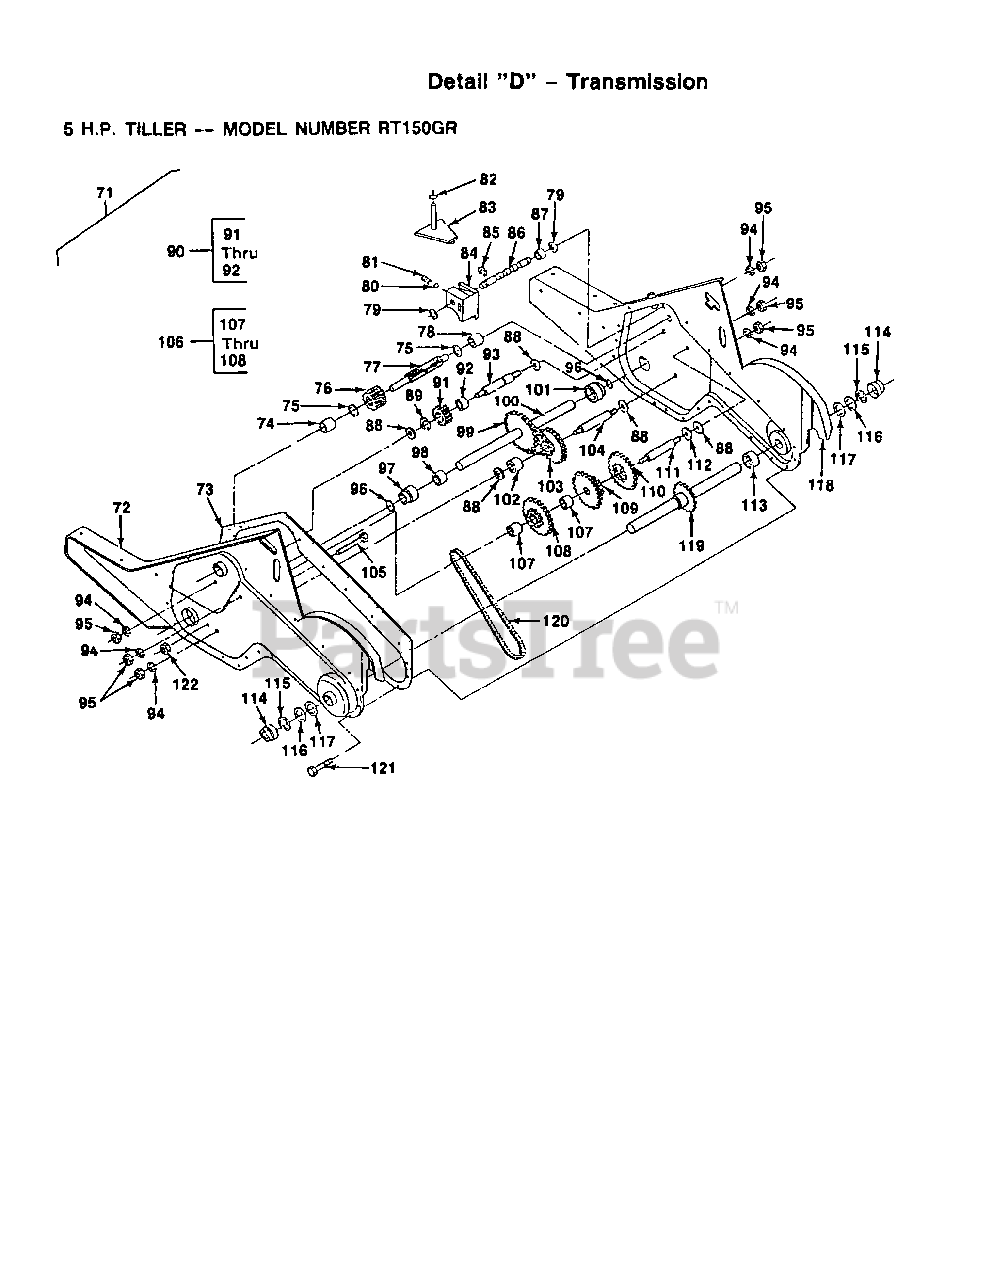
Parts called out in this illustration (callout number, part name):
73	GASKET TI
74	NEEDLE BRNG LT
75	"T, BEARING"
76	PINION-INPUT CRT
77	SHAFT-INPUT CRT
78	"TI, BEARING"
79	WASHER SEAL CRT
81	SPRING-SHIFT CRT
82	O-RING TI
83	ARM ASSY CRT
84	SHIFT FORK TI
85	KLIP RING
86	SHAFT SHIFT CRT
87	SPACER SPLIT CRT
88	WASHER
89	KLIP RING
90	GEAR ASSY CRT
91	GEAR-REV IDLR CRT
92	NEEDLE BEARING TI
93	SHAFT CRT
94	LOCKWASHER
95	NUT.ASF.HEX.7/16
96	O RING CRT
97	"CRT, BEARING"
98	BUSHING TI
99	CHAIN CRT
102	SPACER TI
103	SPRCKT 8 GEAR CRT
104	SHFT 2ND RED. CRT
105	SCRW WHIZ LOK CRT
107	BEARING
109	GEAR TI
110	GEAR TI
111	REDUCTION SHFT TI
112	BRNG RACE
113	SPACER TI
114	CUP.FORMED.
115	RING SPIRAL CRT
119	SHAFT ASSY TI
120	CHAIN.50 LINK TI
121	SCREW CRT
122	NUT.HEX.5/16-18
